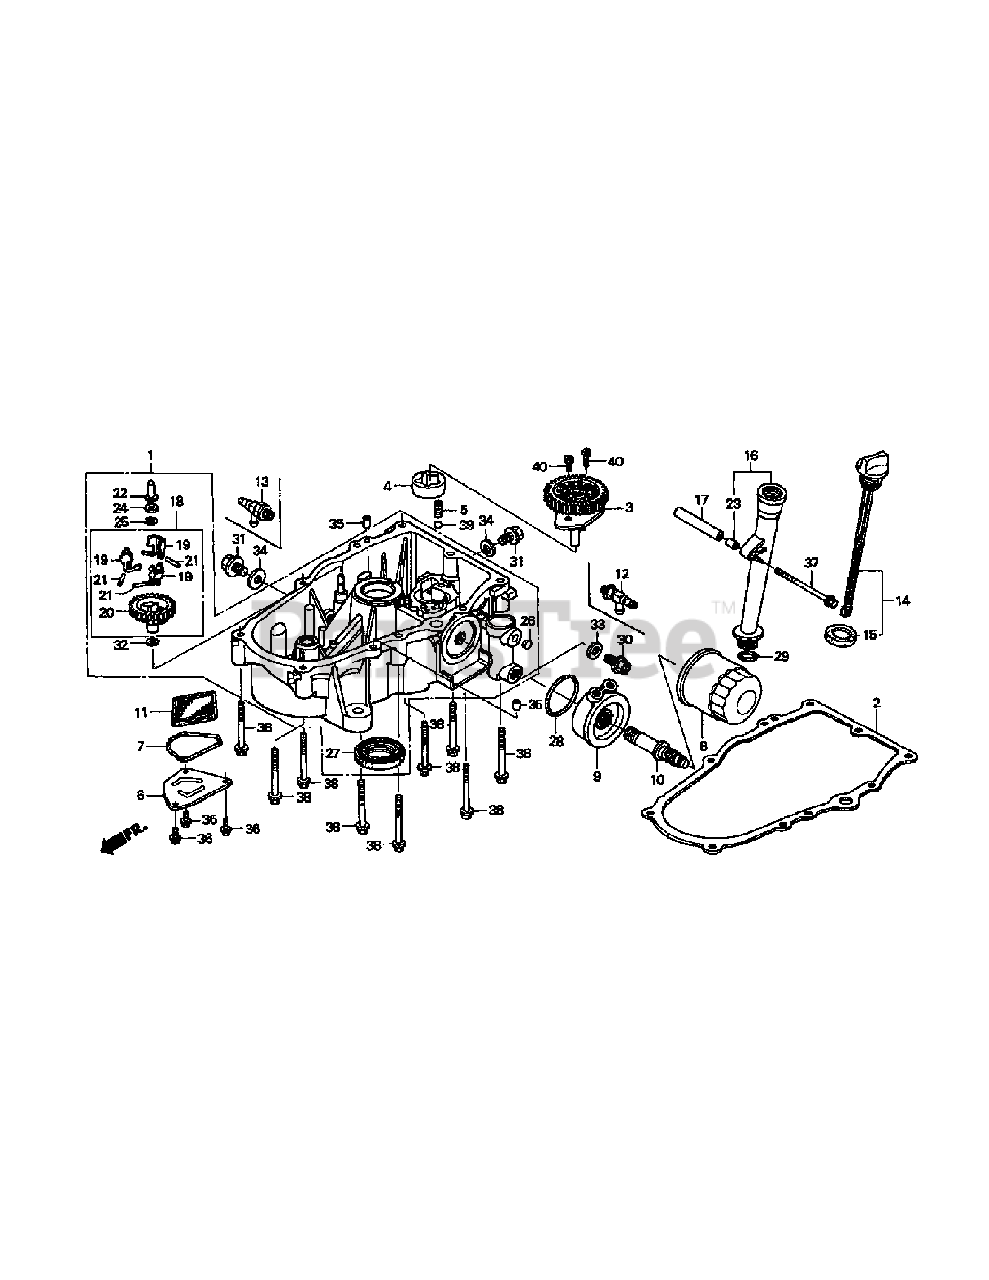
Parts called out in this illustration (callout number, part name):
1	Oil Pan Assy.
2	Case Cover Gasket
3	Oil Pump Cover Assy.
4	Oil Pump Rotor (Outer)
5	Relief Valve Spring
6	Oil Filter Plate
7	Oil Plate O-Ring
8	Oil Filter
9	Oil Filter Base
10	Oil Filter Bolt
11	Oil Filter Screen
12	Drain Valve (14x1.5)
13	Oil Shut-Off Valve
14	Oil Filler Cap Assy.
15	Oil Filler Cap Gasket
16	Oil Filler Extension
17	Filler Setting Collar
18	Governor Assy.
19	Governor Weight
20	Governor Weight Holder
21	Governor Weight Pin
22	Governor Slider
23	Extension Collar
24	Washer (6x16)
25	Governor Holder Clip
26	Sealing Plug (10mm)
27	Oil Seal (38x58x9)
28	O-Ring (51.6x2.3)
29	O-Ring (22.5x2.2)
30	Drain Plug Bolt (14mm)
31	Drain Plug Bolt (20mm)
32	Plain Washer (6mm)
33	Drain Plug Washer (14mm)
34	Drain Plug Washer (20mm)
35	Dowel Pin (8x14)
36	Flange Bolt (6x14)
37	Flange Bolt (6x100)
38	Flange Bolt (8x50)
39	Steel Ball (#12) (3/8)
40	Socket Bolt (6x16)
